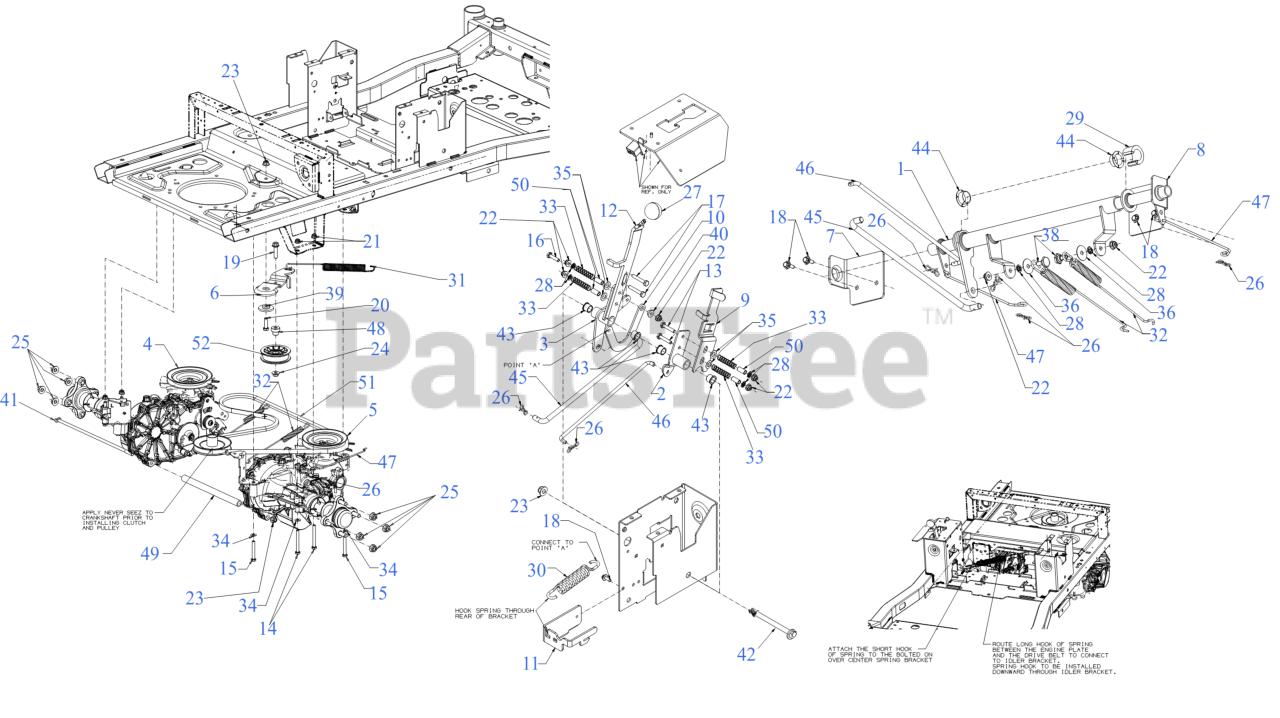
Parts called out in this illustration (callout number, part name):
1	BRAKE PIVOT SHAFT
2	BYPASS LEVER PIVOT ARM
3	PARK BRAKE PIVOT ARM
4	TRANSMISSION (LH)
5	TRANSMISSION (RH)
6	HYDRO DRIVE IDLER BRACKET
7	BRAKE SHAFT SUPPORT (RH)
8	BRAKE SHAFT SUPPORT (LH)
9	TRANSMISSION BYPASS LEVER
10	OVER CENTER LINK
11	SPRING MOUNTING BRACKET
12	PARK BRAKE LEVER
13	HEX SCREW 1/4-20 x 1.25
14	HEX SCREW 5/16-18 x 2.75
15	HEX SCREW 5/16-18 x 2.25 GR5
16	SCREW 1/4-20 X1.00 GR5
17	SCREW 1/4-20 x 1.50 GR.5
18	SCREW M6-1 x .625
19	HEX HEAD BOLT (3/8-16:1.50 GR8)
20	SCREW 3/8-16 x 1.25 GR5
21	FLANGE LOCK NUT 5/16-18
22	FLANGE LOCK NUT
24	FLANGE LOCK NUT
25	HEX FLANGE NUT 7/16-14
26	BOW TIE COTTER PIN 1/4-5/16
27	PARK BRAKE BALL KNOB
28	RETAINER-BOLT .25ID x .50OD
29	SPACER: .76ID x .75
30	EXTENSION SPRING .57 x 5.38
31	EXTENSION SPRING .75 DIA X 10.27
32	EXTENSION SPRING .60 DIAx9.09
33	COMPRESSION SPRING
34	FLAT WASHER
35	WASHER THRUST .375X.70X.030
36	FLAT WASHER
38	SHOULDER SCREW
39	SHOULDER SPACER
40	SHOULDER SPACER
41	SUPPORT TUBE ROD
42	SHOULDER SCREW .491x3.937 3/8-16
43	FLANGE BUSHING
44	FLANGE BEARING .75 x 1.125 x .375
45	BRAKE LINK
46	BYPASS LINK
47	HYDRO BYPASS ROD
48	SHOULDER SPACER
49	SUPPORT TUBE
50	SPACER .252x.350x.760
51	TRANSMISSION DRIVE BELT A x 67
52	FLAT IDLER PULLEY 3.00 OD
